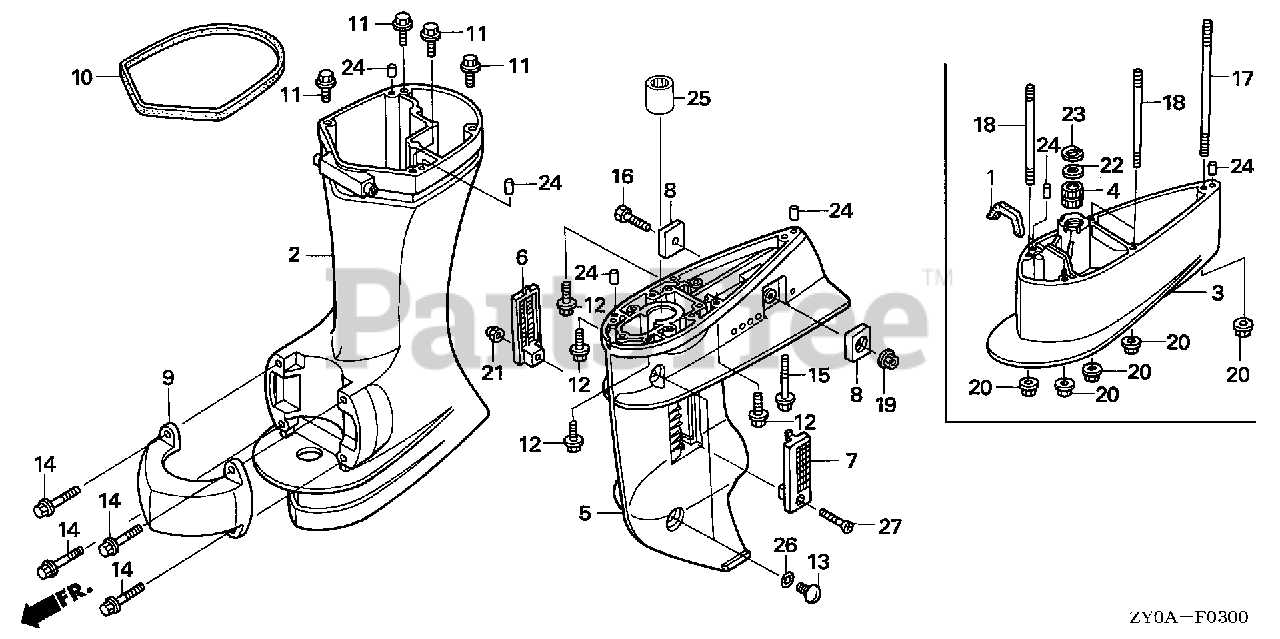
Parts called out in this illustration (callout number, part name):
1	GROMMET, WATER PUMP HOUSING
2	CASE, EXTENSION *NH282MU* (L) (OYSTER SILVER METALLIC-U)
3	SEPARATOR, EXTENSION *NH282MU* (UL) (OYSTER SILVER METALLIC-U)
4	BUSH, VERTICAL SHAFT
5	CASE, GEAR *NH282MU* (OYSTER SILVER METALLIC-U)
6	SCREEN, R. WATER
7	SCREEN, L. WATER
8	METAL, ANODE
9	HOUSING, MOUNTING (LOWER) *NH282MU* (OYSTER SILVER METALLIC-U)
10	RUBBER, COVER (LOWER)
11	BOLT, FLANGE (8X35)
13	BOLT, OIL CHECK
14	BOLT, FLANGE (6X20)
16	BOLT, HEX. (6X25)
17	BOLT, STUD (6X211)
18	BOLT, STUD (6X162)
19	NUT, SELF-LOCK (6MM)
20	NUT, SELF-LOCK (6MM)
21	NUT, SELF-LOCK (5MM)
22	WASHER (20MM)
23	CIRCLIP (INNER) (30MM)
24	PIN, DOWEL (6X10)
25	BEARING, NEEDLE (15X22X20)
26	O-RING (6.9X1.45)
26	O-RING (5.5X1.5)
27	SCREW, OVAL (5X28)
